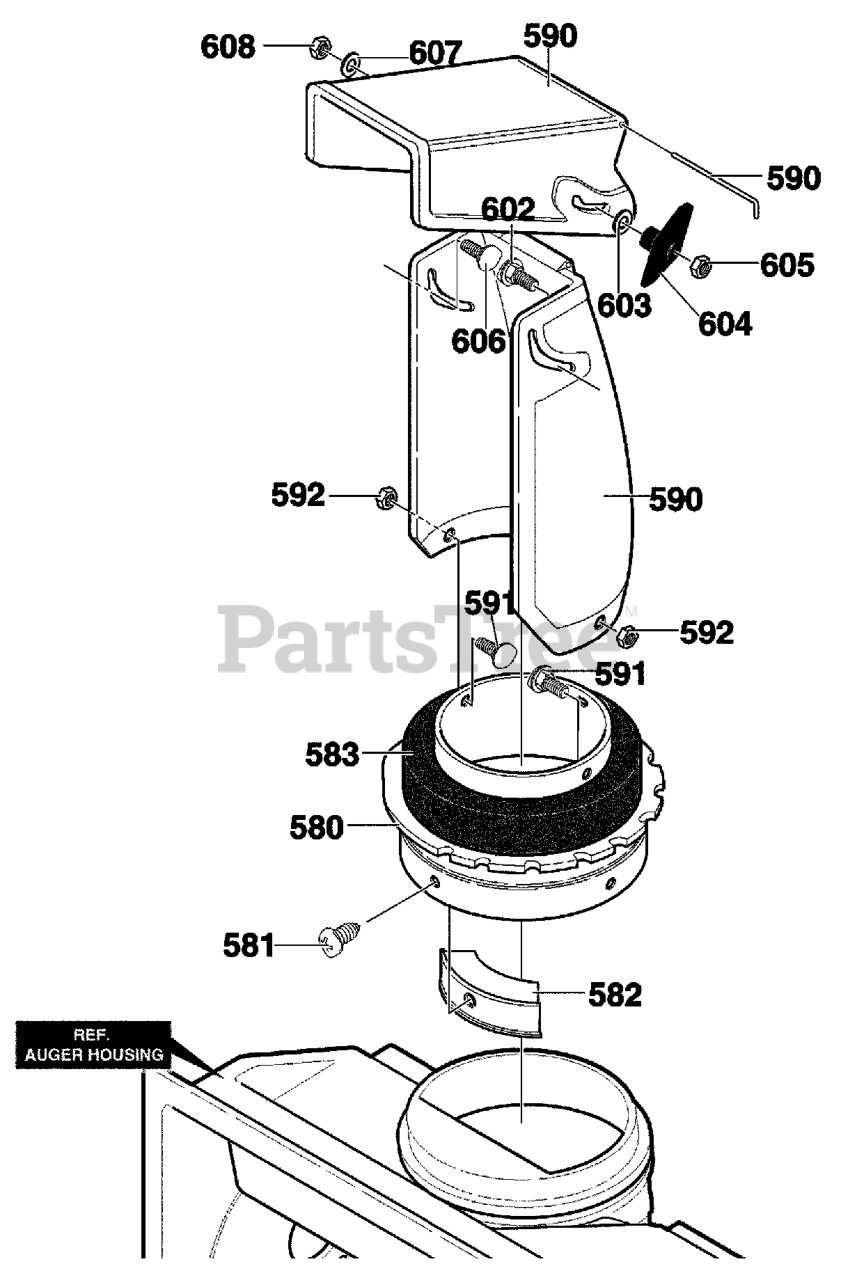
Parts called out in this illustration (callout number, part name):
580	RING, CHUTE
581	SCREW, #10X.50
582	GUIDE, CHUTE
583	DONUT FOAM
590	CHUTE ASSY.
591	SCREW 1/4-20X.50
592	NUT, 1/4-20
602	BOLT, 5/16-18X1.25 CARR.
603	WASHER, FLAT .349X.69X.066
604	KNOB, T
605	NUT, 5/16-18
606	SCREW, 5/16-18 x 0.75
607	WASHER, FLAT .349X.69X.066
608	NUT, 5/16-18
